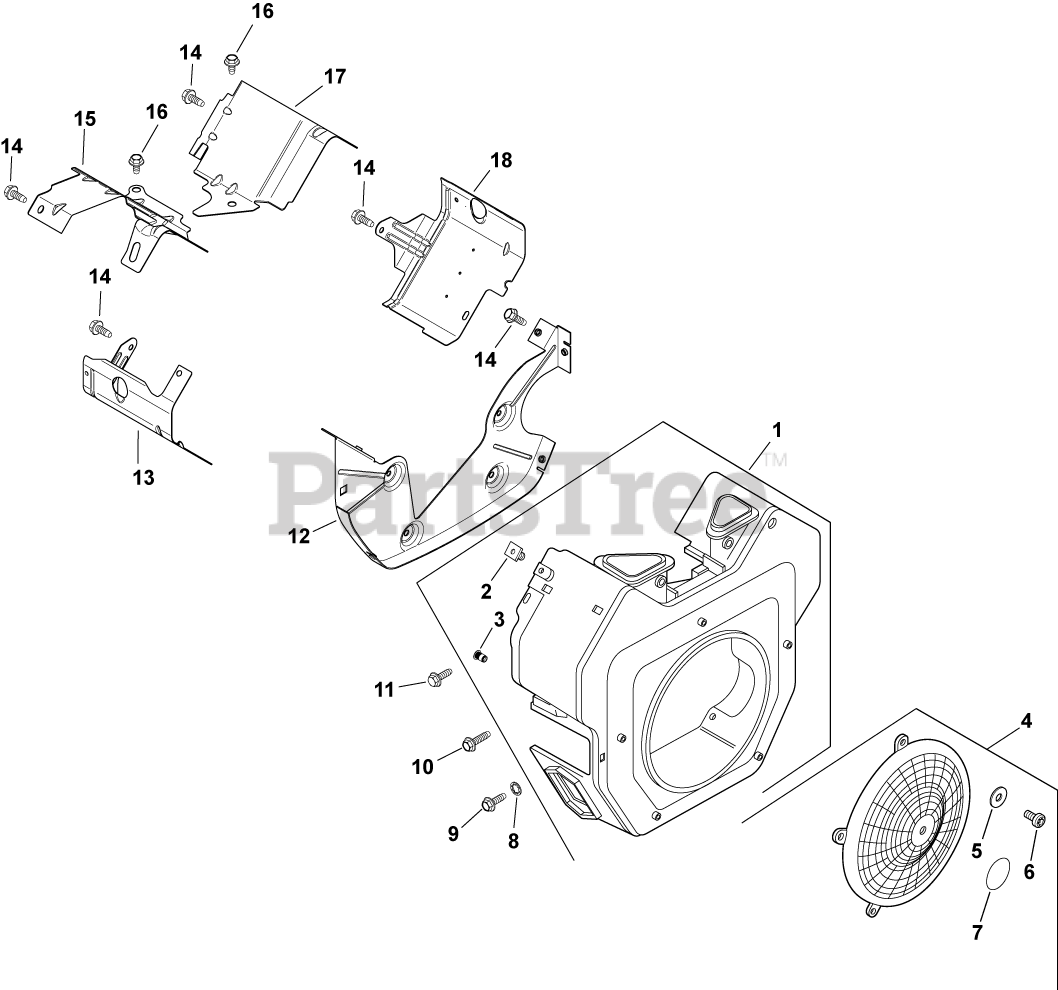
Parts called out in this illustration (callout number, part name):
1	KIT, BLOWER HOUSING USE 24 027 478-S
2	NUT, PLASTIC (KM)-USE 25 100 37-S
3	INSERT, THREADED USE 25 332 19-S
4	KIT, FIXED GUARD
5	WASHER, FLAT 7/32"
6	SCREW, LBD SCKT PAN M5X0.8X10
7	DECAL, GRASS SCREEN USE 24 113 499-S
8	WASHER, INT TOOTH LOCK 1/4"
9	SCREW - USE M-545016-S
10	SCREW,FLG THD FRM M5X0.8X16-(#25086398S)
11	SCREW, FLG THD FRM M5X.8X20-(#25086399S)
12	PLATE, BACKING-USE 24 146 59-S
13	BAFFLE, LEFT BARREL -USE 24 063 88-S
14	SCREW,FLG THD FRM M6X1.0X16-(#25086397S)
15	BAFFLE, VALLEY #2 SIDE-USE 24 063 94-S
16	SCREW, FLG THD FRM M5X.8X10
17	BAFFLE, VALLEY (CH)-USE 24 063 93-S
18	BAFFLE, RIGHT BARREL-USE 24 063 85-S
